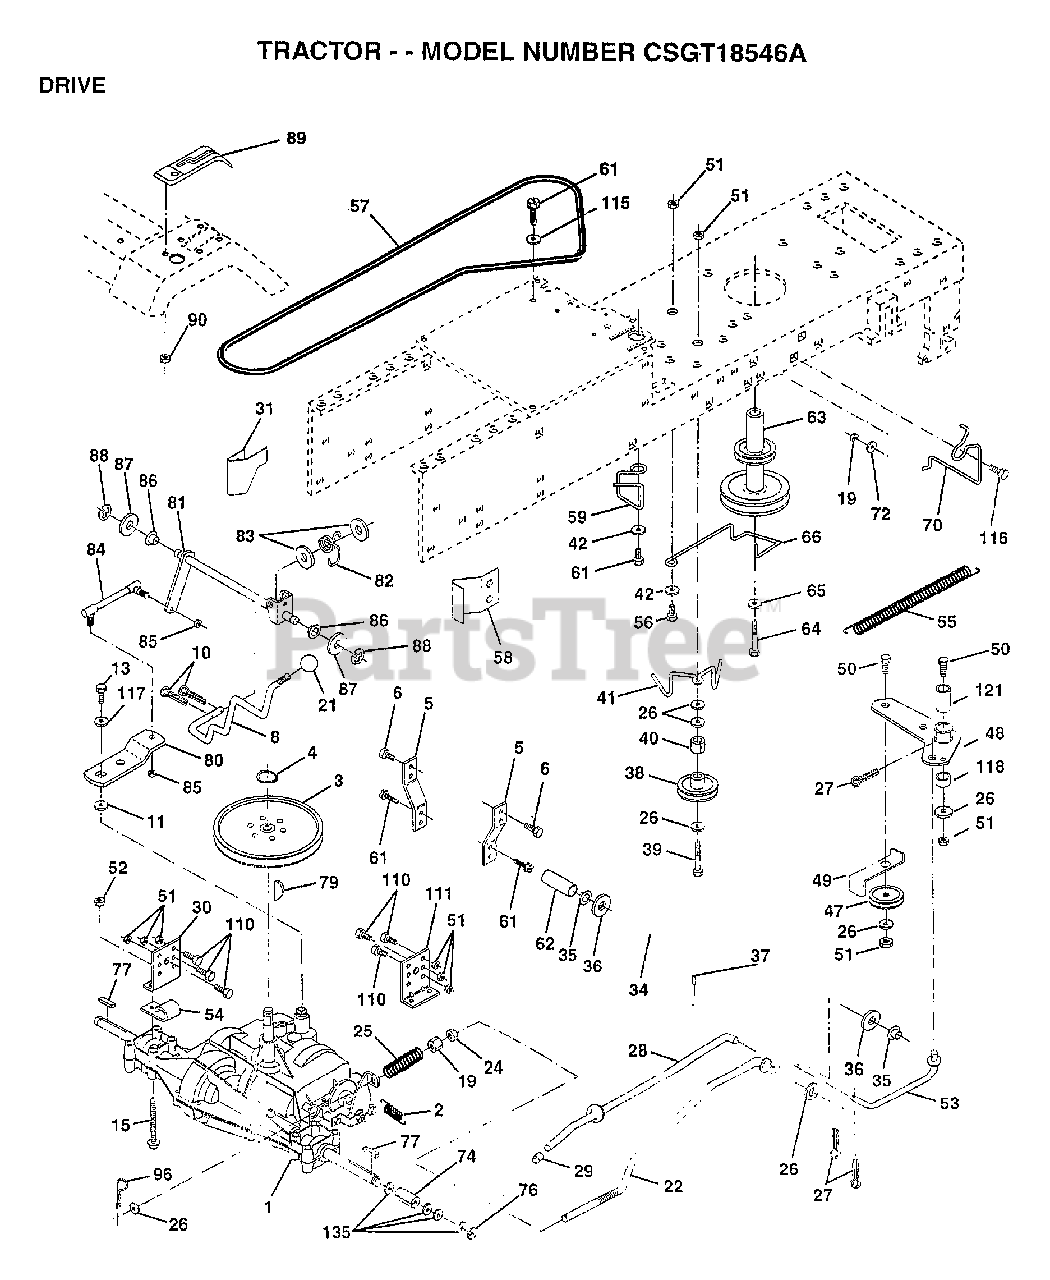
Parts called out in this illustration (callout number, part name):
1	TRANSAXLE PEERLESS
3	PULLEY TRANSAXLE
4	RING
5	STRAP TORQUE
6	SCREW
8	ROD SHIFT FEND YT
10	PIN COTTER 1/8
11	WASH-SHFT PLT LT
13	BOLT.1/4-28.W/PAT
15	BOLT.HX.FLG.5/16
19	NUT
21	KNOB T (1/2-HOLE)
22	ROD.ASM.BK.44.MWR
24	NUT
25	"SPRING,ROD BRAKE"
26	WASHER
27	COTTER PIN
28	ROD.BRAKE.PARK.LT
29	PLUNGER CAP T
30	BRKT TRANS LH
31	KEEPER BELT LH
32	BOLT
34	SHAFT ASM-PEDAL F
35	NYLON BEARING
36	WASHER LT
38	PULLEY.IDLER.FLAT
39	BOLT
40	SPACER T
42	WASHER
48	BELLCRANK ASM
49	RETAIN BELT
53	"LINK, CLUTCH T"
54	"CLIP,INSULATOR"
55	"SPRING, RETURN LT"
57	BELT.GRDRV.94.75
58	"KEEPER,BELT RH"
59	KEEPER BELT CNTSP
61	SCREW
62	PEDAL COVER T
64	BOLT
65	LOCKWASHER
66	KEEPER-BELT
70	"GUIDE.BELT,RH ENG"
72	WASHER
74	SPACER HYT
76	E RING HYT
77	SQ KEY STD
80	HARNESS IGNITION
81	"SHAFT,SHIFTER"
82	"SPRING,TORSION"
83	WASHER
84	"ROD LINK,SHIFT AD"
85	NUT.CNT.LOCK.1/4
86	BUSHING
87	WASHER D
88	KLIP RING
89	CONSOLE SHIFTER
90	NUT
96	RETAINER M
111	BRKT TRANS RH
115	WASHER GT
116	BOLT RDHD 3/8-16
117	WASHER PM
118	SPACER-BELLCRANK
121	NYLINER-CLUTCHING
135	WASHER
